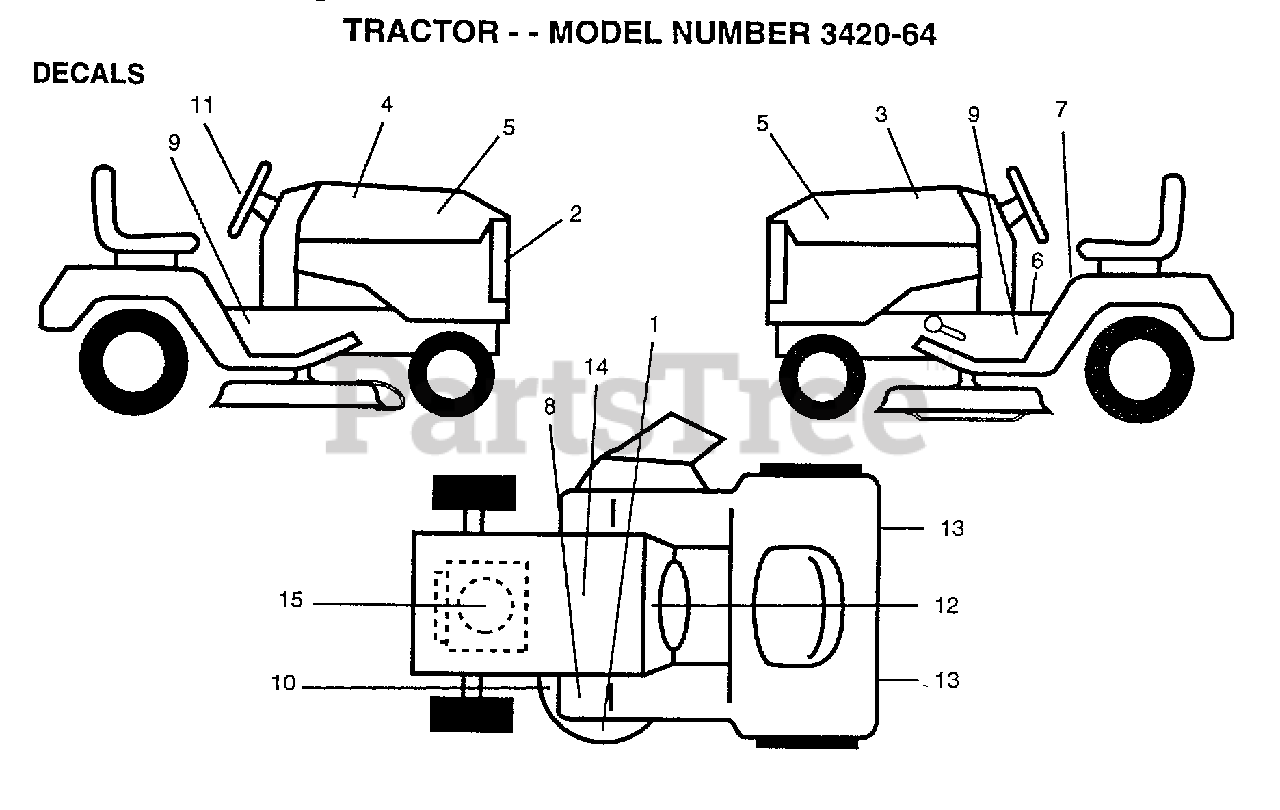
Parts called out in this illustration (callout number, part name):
2	GRILL DECAL
3	HOOD DECAL LH
5	NAMEPLATE LOGO
6	DECAL BRAK PARK
7	DECAL
9	DECAL.CHAS.16.5
10	DECAL
12	DECAL.DASH.INST.
13	REFLECTOR-TAIL YT
14	DECAL.BTRY.DANGER
15	DECAL, HP ENGINE
